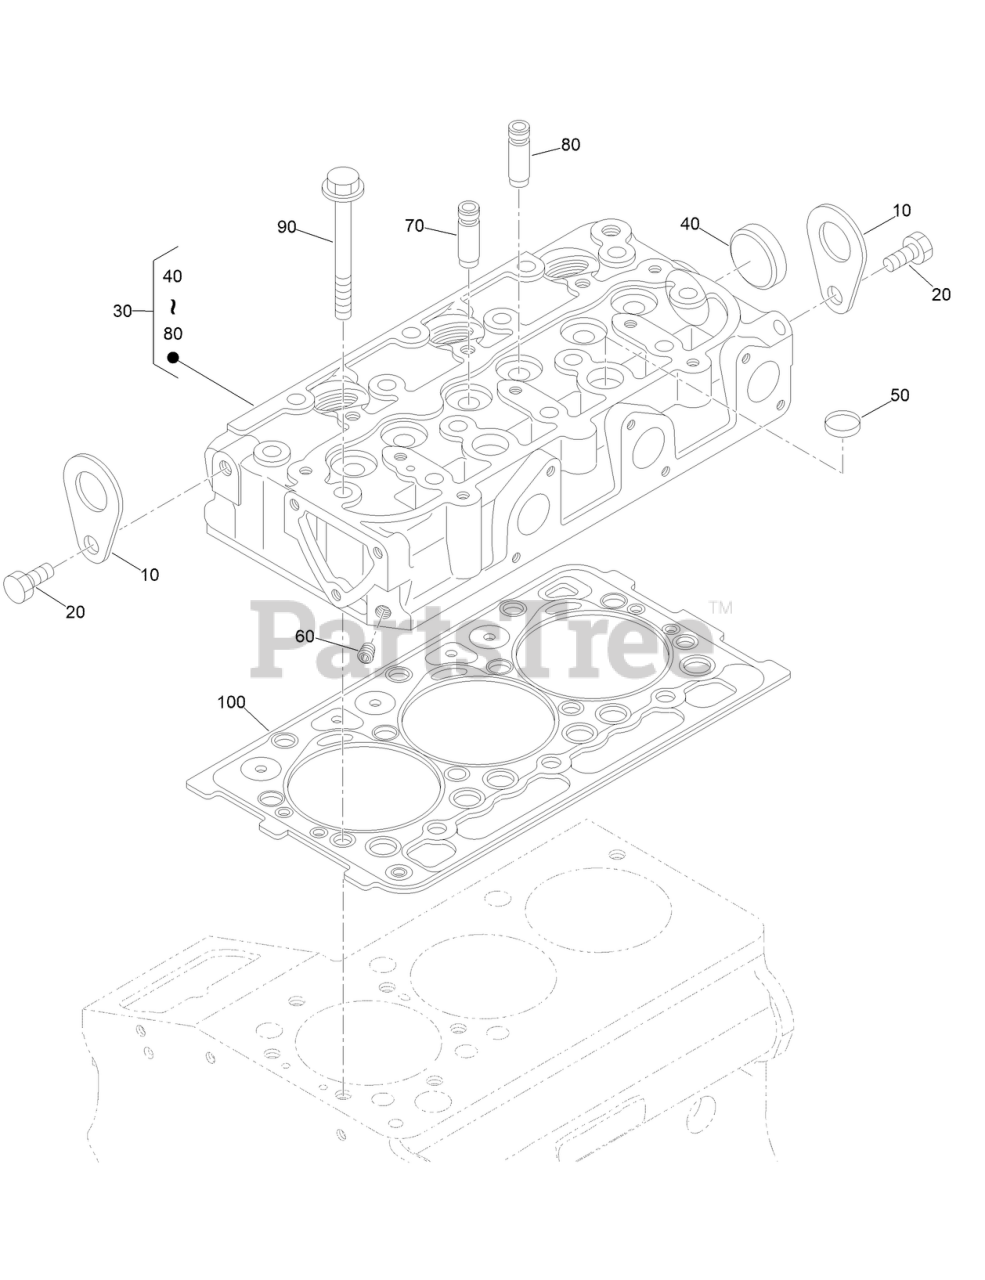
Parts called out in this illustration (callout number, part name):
10	HOOK-ENGINE
20	BOLT,SEMS
30	CYLINDER HEAD ASM
40	CAP-SEALING
50	CAP-SEALING
70	GUIDE-VALVE, INLET
80	GUIDE-VALVE, EXHAUST
90	BOLT,HEAD(CYLINDER)
100	GASKET-HEAD, CYLINDER
